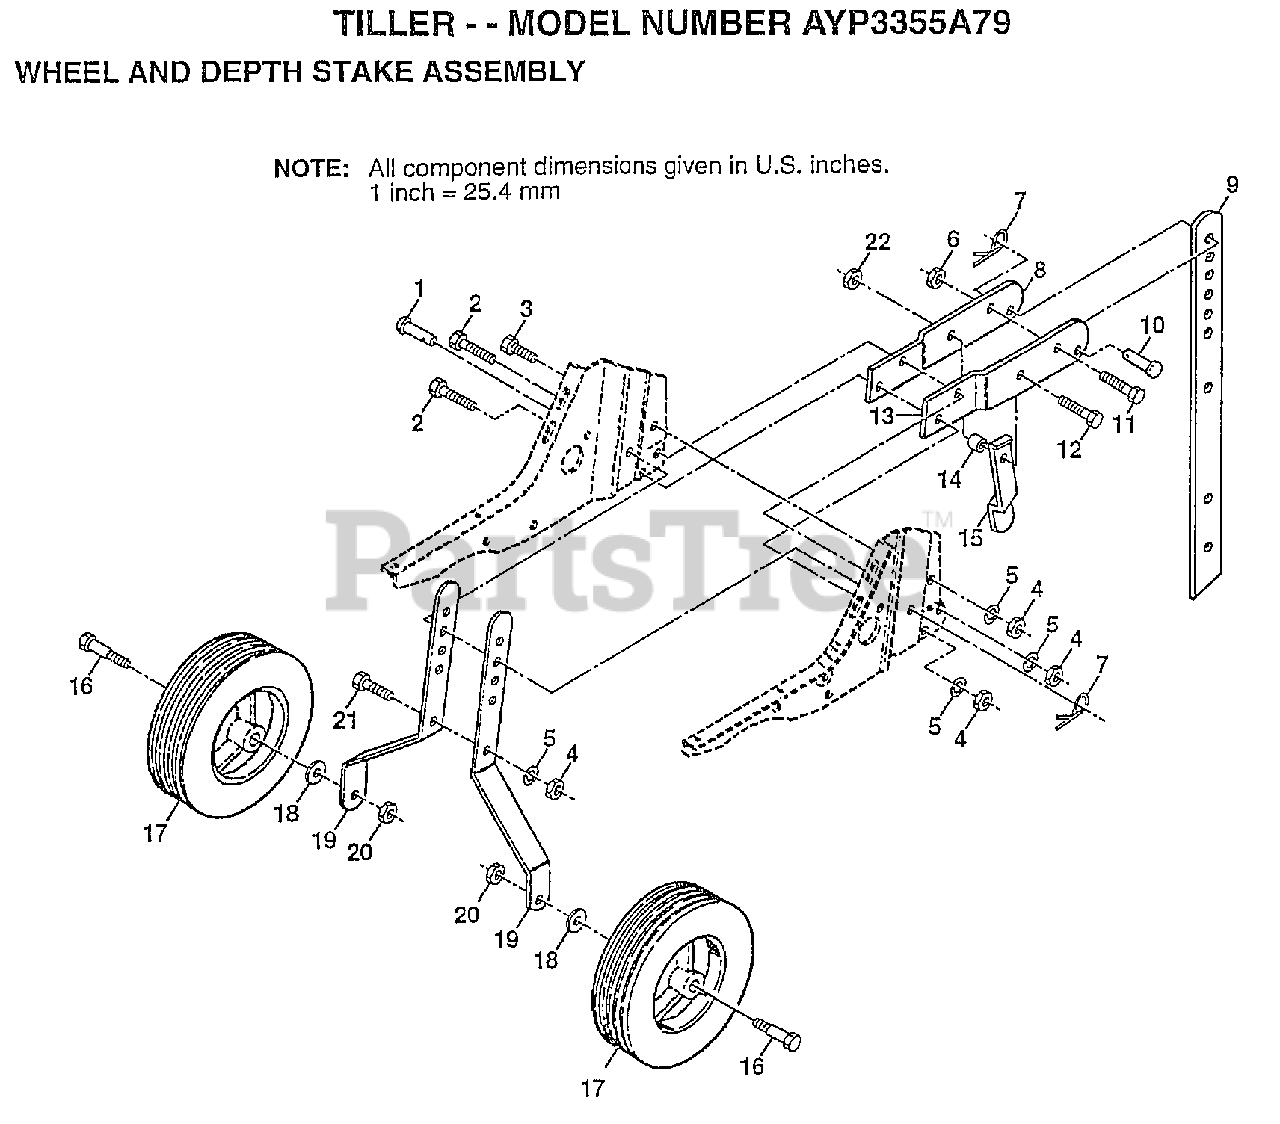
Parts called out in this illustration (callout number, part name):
1	DRILLED RIVET RT
3	BOLT
4	NUT.HEX.5/16-18
5	LOCKWASHER
6	NUT
7	SPRING.RETAINER
11	BOLT
12	BOLT.HEX.5/16-1.5
14	WASHER
15	STAKE SPRING TI
16	BOLT SHOULDER
18	WASHER
22	NUT
